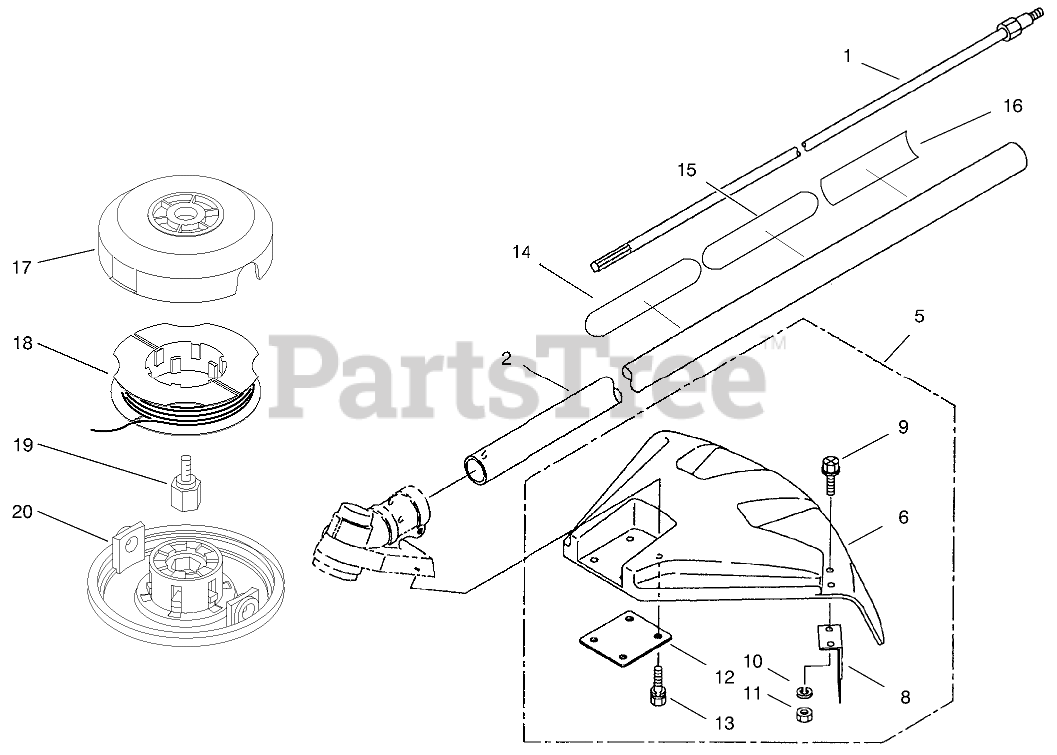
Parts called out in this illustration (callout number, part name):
1	ASM - DRIVESHAFT
2	Driveshaft Tube Assembly (Incl. Ref. #14,15)
5	Safety Cover Assembly (Incl. Ref. # 6-13)
6	COVER - SATETY
8	CUTTER - STRING
10	WASHER - SPRING
11	NUT M5
12	PLATE
14	DECAL - CAUTION
15	DECAL - CAUTION
16	DECAL - TORO
18	SPOL W/ LINE
19	MOUNTING STUD
20	INDEXING BASE
